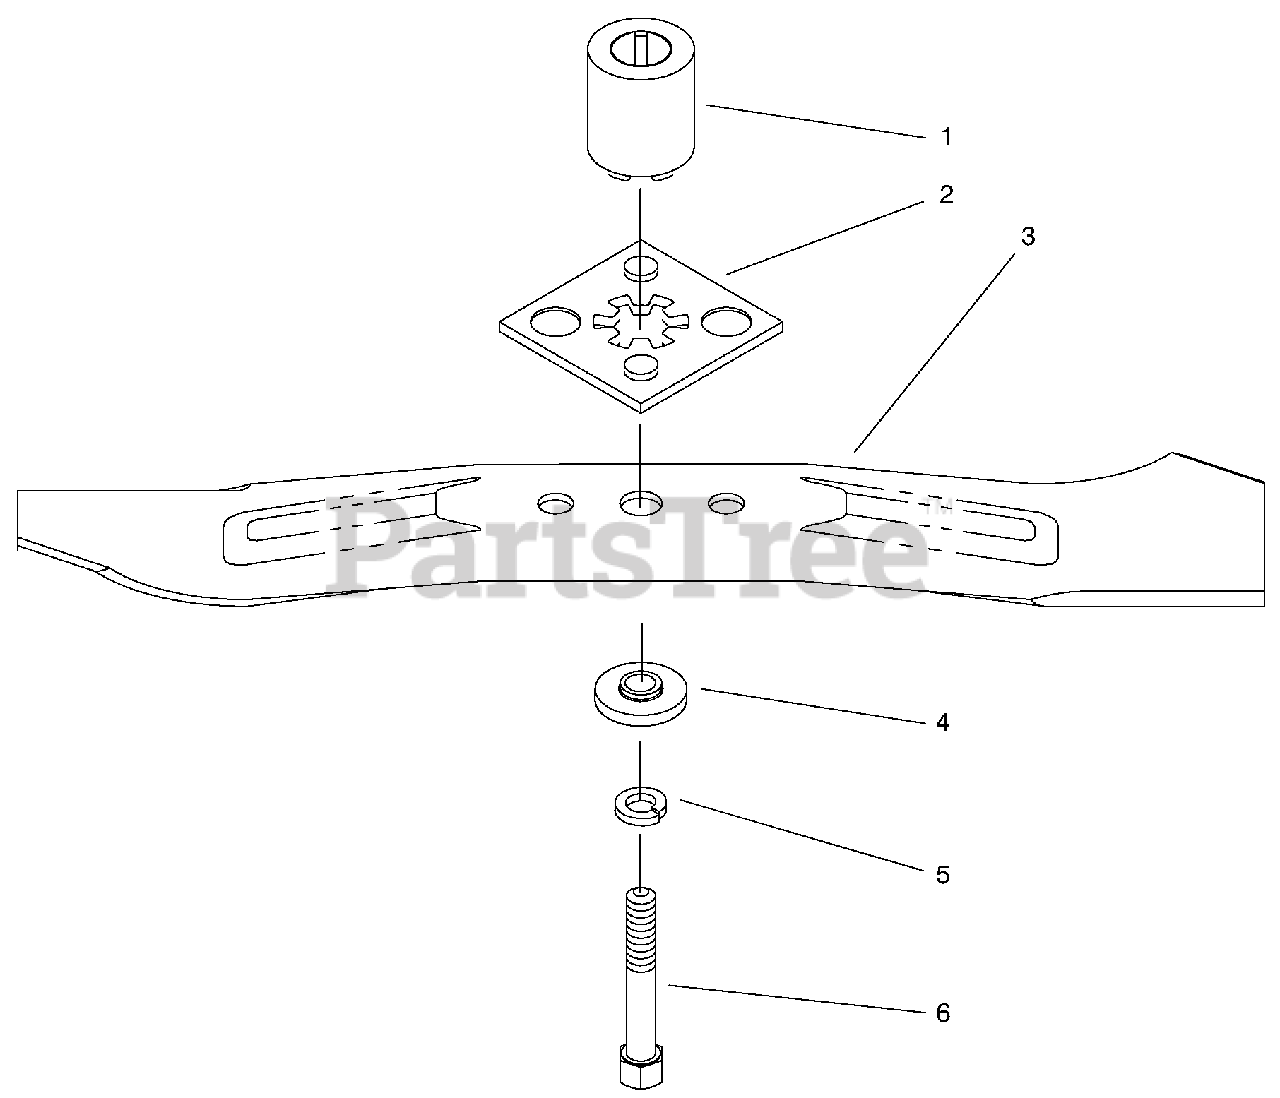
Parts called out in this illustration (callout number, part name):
2	PLATE DR
3	Blade
4	SPACER-BLADE
5	WASHER-LOCK
6	SCREW-BLADE
